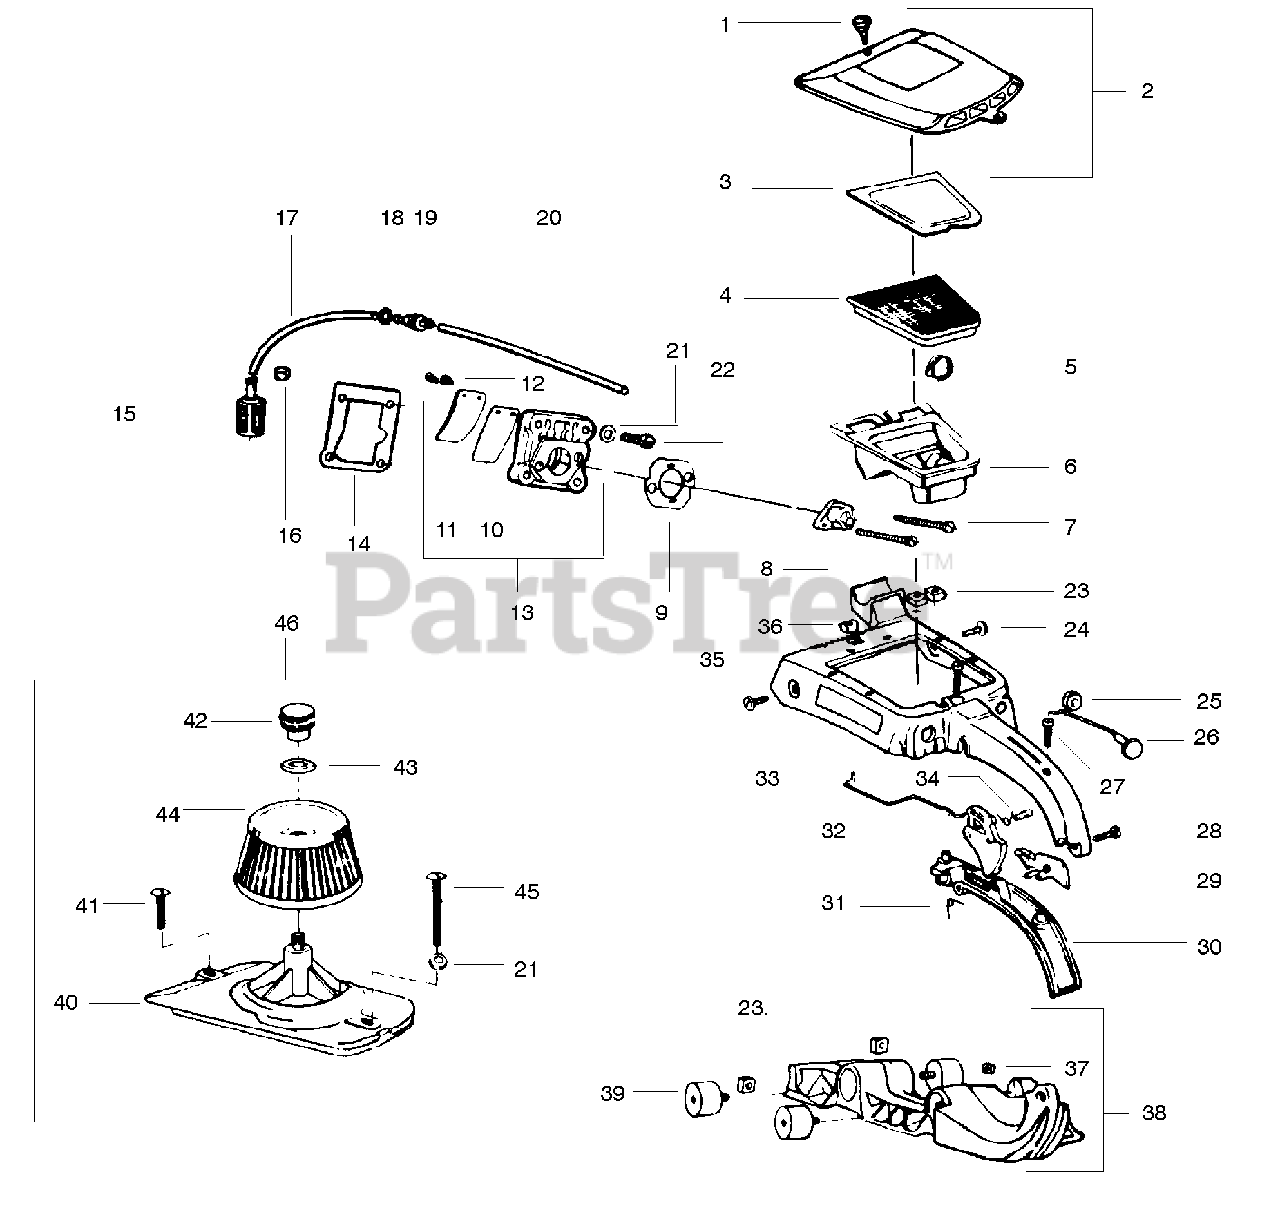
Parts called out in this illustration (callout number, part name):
1	Top Cover Knob
2	Top Cover Ass'y. Complete
3	Air Filter (F)
4	Air Filter (H)
6	Air Box Boot
8	Blow Back Tube
10	Reed Valve
11	Reed Back Plate
12	Reed Screw
13	Reed Valve Ass'y.
15	Fuel Filter Ass'y.
16	Speed Clip
17	Fuel Hose
19	Connector
20	Fuel Hose
26	Choke Knob & Wire Ass'y.
29	Throttle
30	Lower Grip Ass'y.
31	Spring
32	Throttle Trigger
33	Throttle Link
34	Throttle Pin
35	Top Frame
38	Bottom Frame & Nut Ass'y.
39	Isolator
40	Filter Base Ass'y.
44	Filter Element
46	Air Filter Kit
